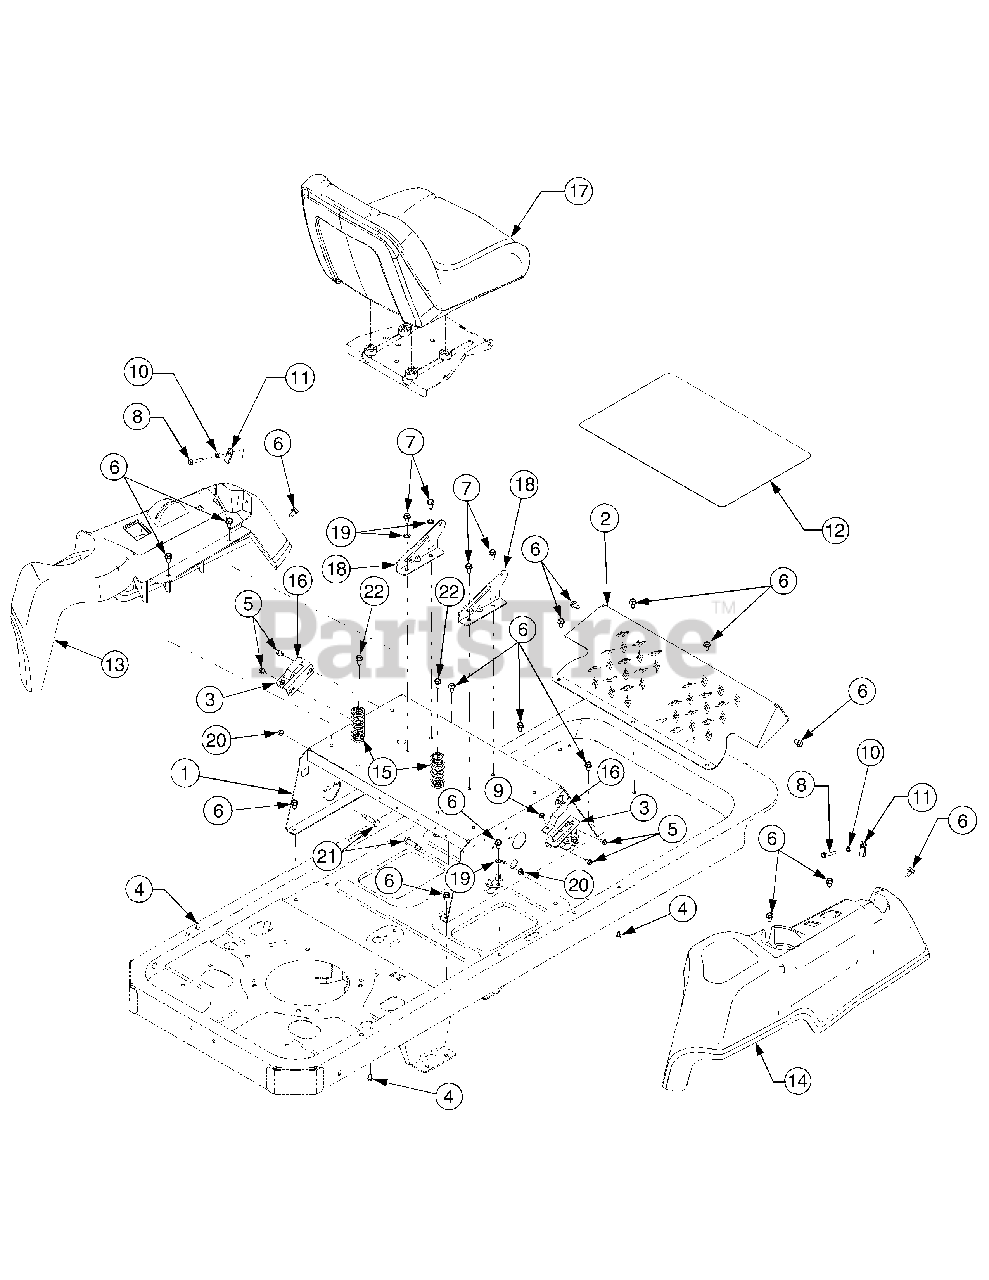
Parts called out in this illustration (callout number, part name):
4	Screw, Hex Wash. Hd Tapp #12-16 x .50
5	Screw, Hex Wash. Hd. Tapp. 1/4-20 x .5
6	Screw, Hex Wash. Hd. Tapp 5/16-18 x .625
7	Screw, Hex Wash. Hd. Tapp 5/16-12 x .75
8	Screw, Hex Wash. Hd. Tapp. 1/4-20 x 1.5
9	Screw, Hex Wash. Hd Tapp #10-16 x .375
10	Nut, Hex Jam, 1/4-20 GR2
11	Nut, U Type Speed, 1/4-20
13	Console, LH
14	Console, RH
15	Spring, Compression, 1.28 x 3.125
16	Spring, Switch Actuator
19	Washer, External Tooth, 3/8
20	Nut, Hex Insert Lock, 1/4-20 - Model ZT 5000 ONLY
21	Screw, Shoulder, .374 x 1.16:1/4-20 -Model ZT 5000 ONLY
22	Screw, Hex Wash. Hd. Tapp 5/16-18 x .75
